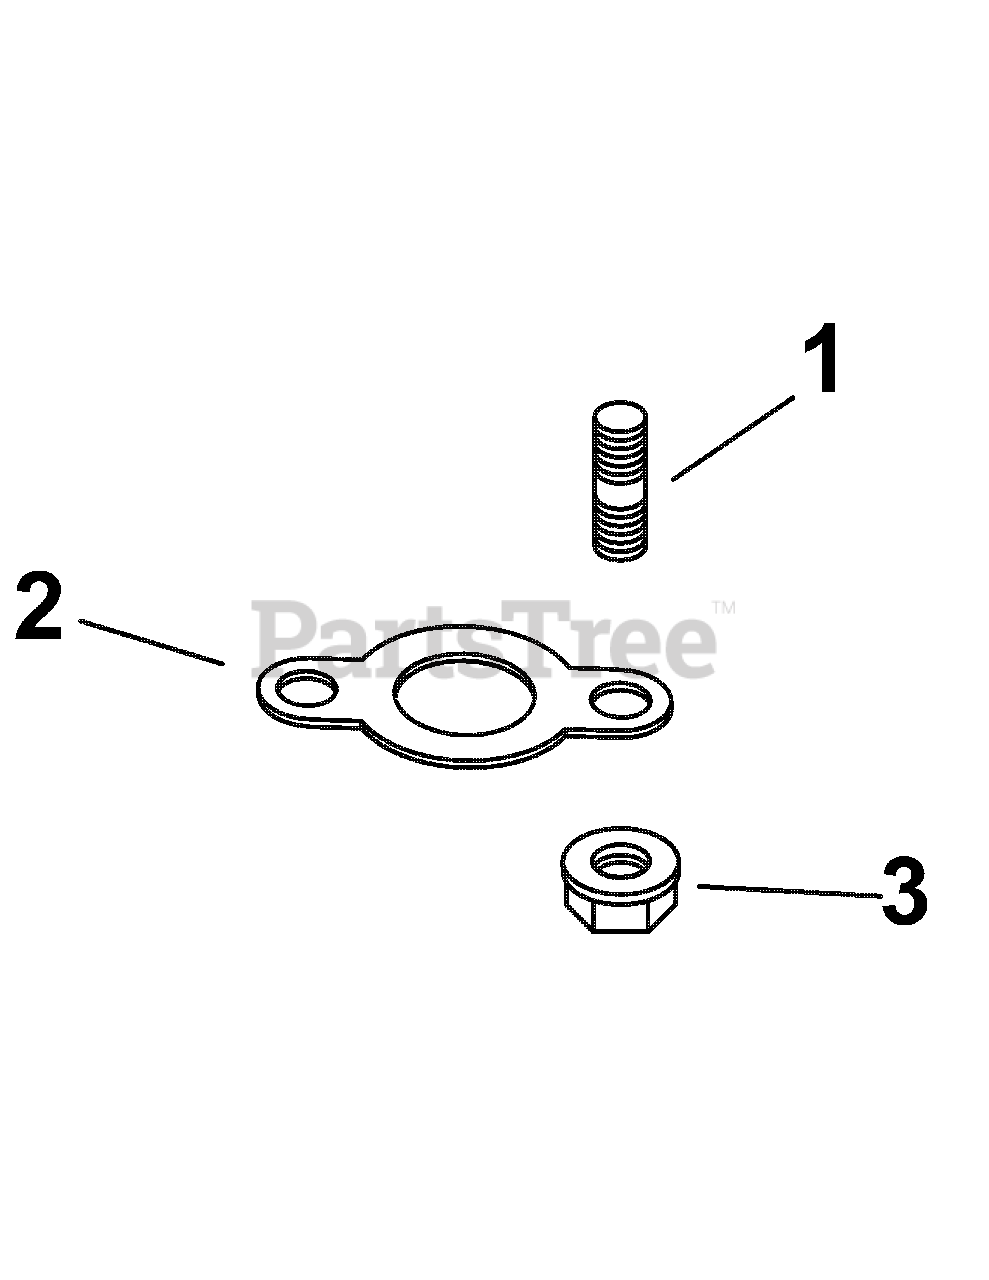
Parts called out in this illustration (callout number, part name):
1	Stud, M8X1.25X33
2	Gasket, Exhaust
3	Nut, Flg M8X1.25
